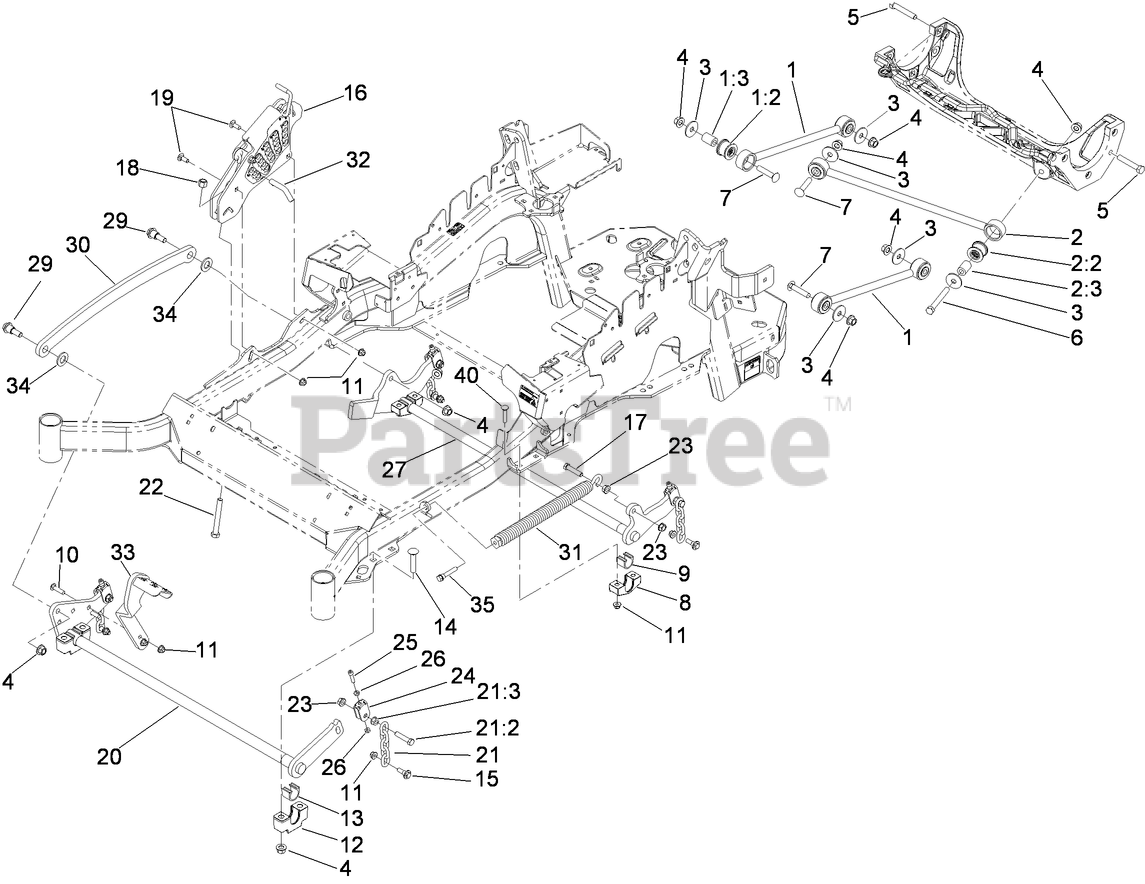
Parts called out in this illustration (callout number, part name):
1	DECK STRUT ASM
1:2	BUSHING-SUSPENSION, RUBBER
1:3	SPACER
2	PANHARD ROD ASM
2:2	BUSHING-SUSPENSION, RUBBER
2:3	SPACER
3	WASHER-THRUST
4	NUT-LOCK
5	SCREW-HH
6	SCREW-HH
7	SCREW-CARR
8	SUPPORT-CROSS SHAFT, REAR BEARING
9	BEARING-CROSS SHAFT, REAR
10	SCREW-CARR
11	NUT-HF, NI
12	SUPPORT-CROSS SHAFT, BEARING
13	BEARING-CROSS SHAFT, FRONT
14	SCREW-CARR, SHORT NECK
15	SCREW-SHOULDER, HHF
16	HOC ASM
17	SCREW-HH
18	NUT-LOCK, NI
19	BOLT-CARR
20	CROSS SHAFT-FRONT
21	DECK LIFT CHAIN ASM
21:2	SCREW-HH
21:3	NUT-HF
22	BOLT-TAP
23	NUT-HF
24	YOKE-ADJUST, DECK
25	SCREW-HSH
26	NUT-JAM
27	LIFT-DECK, REAR
29	SCREW-SHOULDER, HHF
30	LINK-LIFT, DECK
31	SPRING-EXTENSION
32	PIN-HOC
33	LEVER-FOOT
34	WASHER-FLAT
35	BOLT-SHOULDER
40	SCREW-CARR
